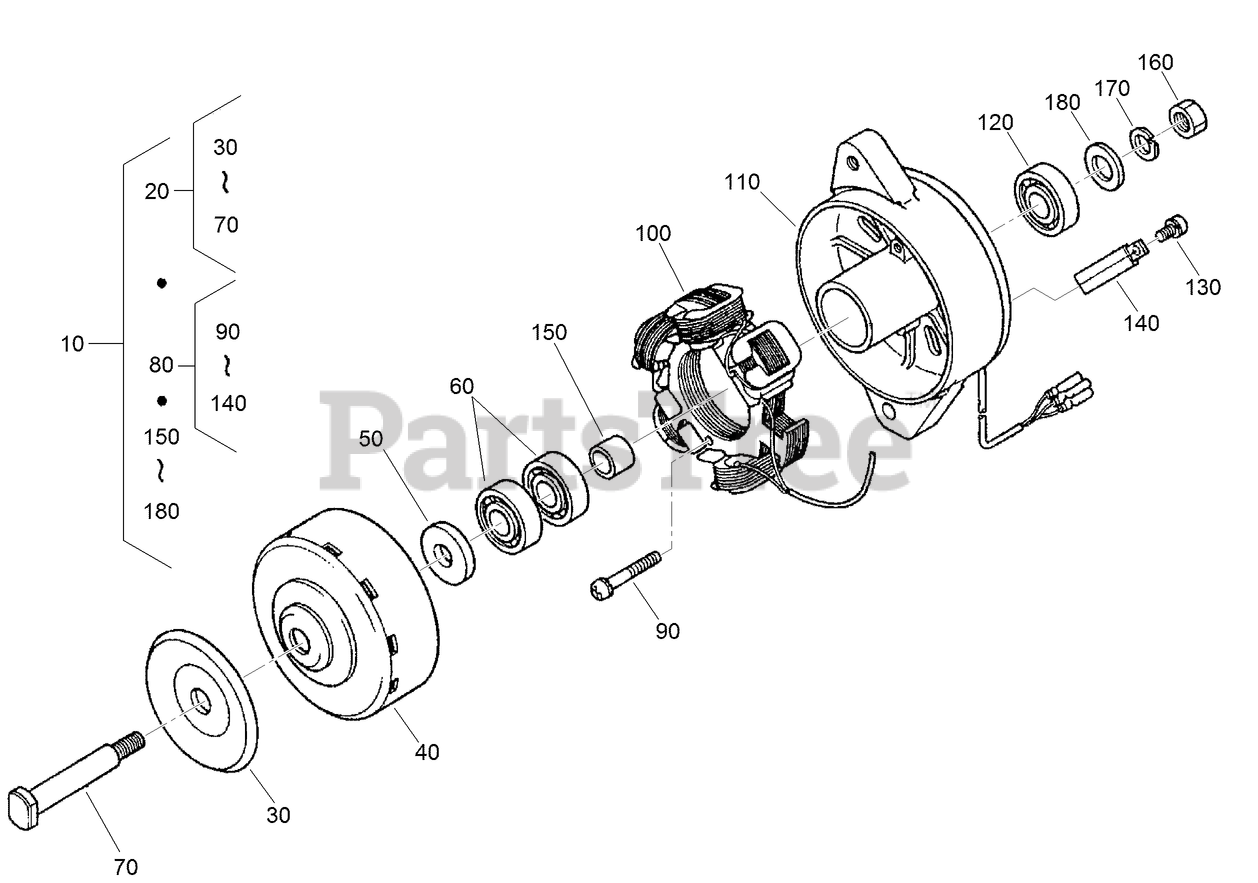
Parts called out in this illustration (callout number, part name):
10	DYNAMO ASM
20	FLYWHEEL ASM
30	PULLEY
40	FLYWHEEL
50	COLLAR
60	BEARING-BALL
70	SHAFT-FAN
80	STATOR ASM
90	SCREW-HEAD, ROUND
100	STATOR
120	BEARING-BALL
130	SCREW-HEAD, ROUND
140	CLAMP-CORD
150	COLLAR
170	WASHER-SPRING
180	WASHER-PLAIN
